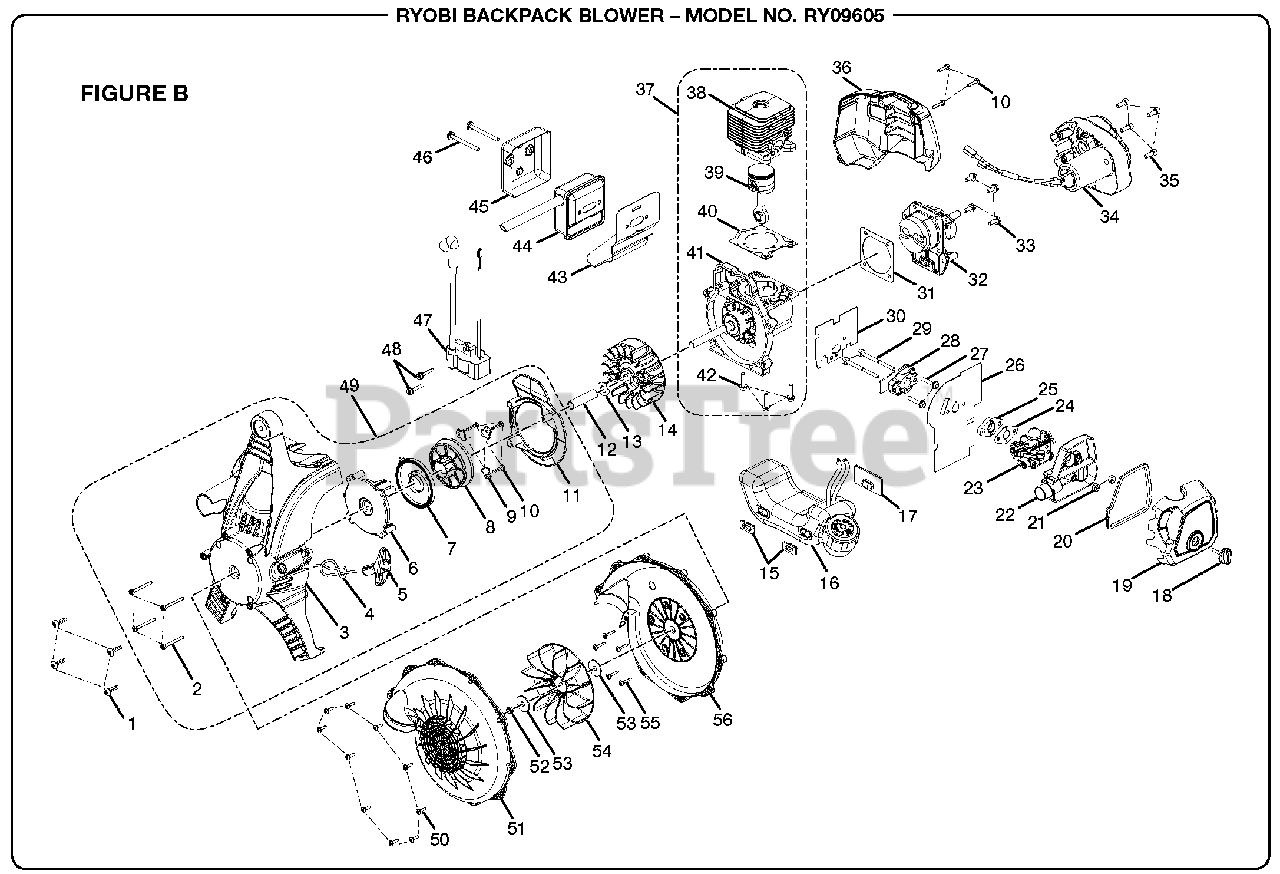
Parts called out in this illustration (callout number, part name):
1	Screw (10-24 x 3/4 in.)
2	Screw (M4 x 38 mm)
3	Lower Housing Assembly
4	Starter Rope (42 in.)
5	Starter Grip
6	Starter Retainer
7	Spring and Container
8	Starter Pulley
9	Pulley Retainer
10	Screw (M4 x 18 mm)
11	Baffle Plate
13	Washer
14	Rotor Assembly
15	Bumper
16	Fuel Tank and Cap Assembly
18	Thumb Screw
19	Air Box Cover
20	Air Box Gasket
21	Lock Nut (10-24)
22	Air Filter Base
23	Carburetor Assembly
24	Carburetor Gasket
25	Gasket
26	Carburetor Gasket
27	Screw (10-24 x 1 in., Pan Hd.)
29	Carburetor Bolt
30	Heat Dam Gasket
31	Crankcase Gasket
32	Crankcase Cover Assembly
33	Screw (10-24 x 3/4 in., Pan Hd.)
34	Electric Start Assembly
35	Screw (M5 x 14 mm)
36	Rear Housing
37	Short Block Assembly (Inc. Key Nos. 38-42)
38	Cylinder
39	Piston w/Rod Assembly
40	Cylinder Gasket
41	Crankcase Assembly
42	Screw (M5 x 20 mm)
43	Muffler Gasket
44	Muffler Assembly
45	Heat Shield
46	Screw (10-24 x 2-1/8 in.)
47	Electric Start Ignition
48	Screw (M4 x 25 mm)
49	Lower Housing w/Starter Assembly (Inc. Key Nos. 2-11)
50	Screw (10-14 x 3/4 in.)
51	Bottom Volute
52	Hex Nut (10-24)
54	Blower Fan
55	Screw (10-14 x 27 mm)
56	Top Volute
